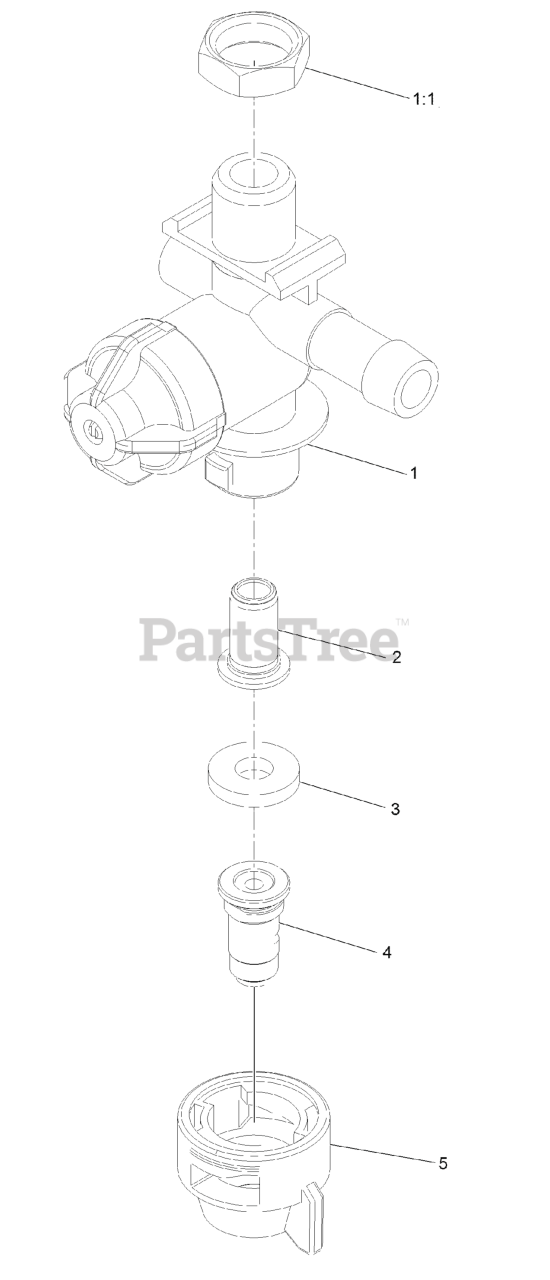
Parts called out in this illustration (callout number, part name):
1	LH NOZZLE BODY ASM
1:1	NUT-NYLON
2	STRAINER-TIP
4	NOZZLE-SPRAY, WHITE
5	CAP-NOZZLE
